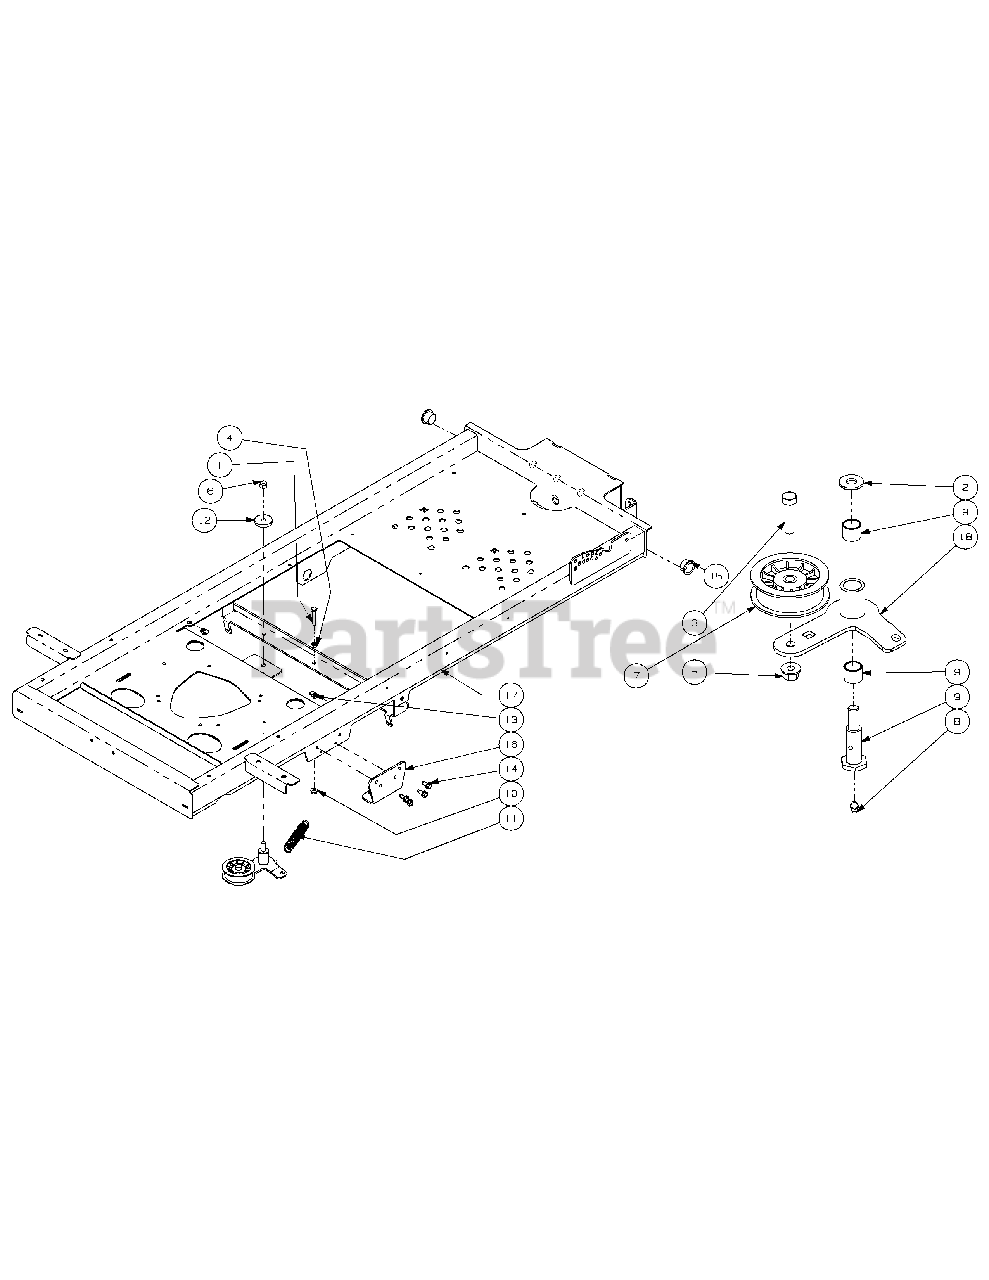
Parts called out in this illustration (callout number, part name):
1	Hex Cap Screw, 5/16-18 x 1-3/4
2	Flat Washer, 3/8 zinc
3	Hex Cap Screw, 3/8-16 x 1-1/2
4	Hex Nut, 5/16-18
5	Hex Nut, 3/8-16 Flange Lock
6	Nylock Nut, 7/16-14
7	Flat Idler Pully w/ adaptor
8	Grease Fitting, 1/4-28 x 3/16
9	Shoulder Bolt
10	Nut, 5/16-18, Hexflange Lock
11	Extension Spring, .865 OD x 4.68 lg
12	Flat Washer, 7/16 ID x 1.75 OD
13	U-Nut, 1/4-20
14	Self Tapping Screw 5/16-18 x .750
15	Bronze Bushing, 1.00 ID x 1.50 OD
16	Transmission Mounting Bracket
17	Frame Assembly Weldment
18	Idler Arm Assembly includes:
